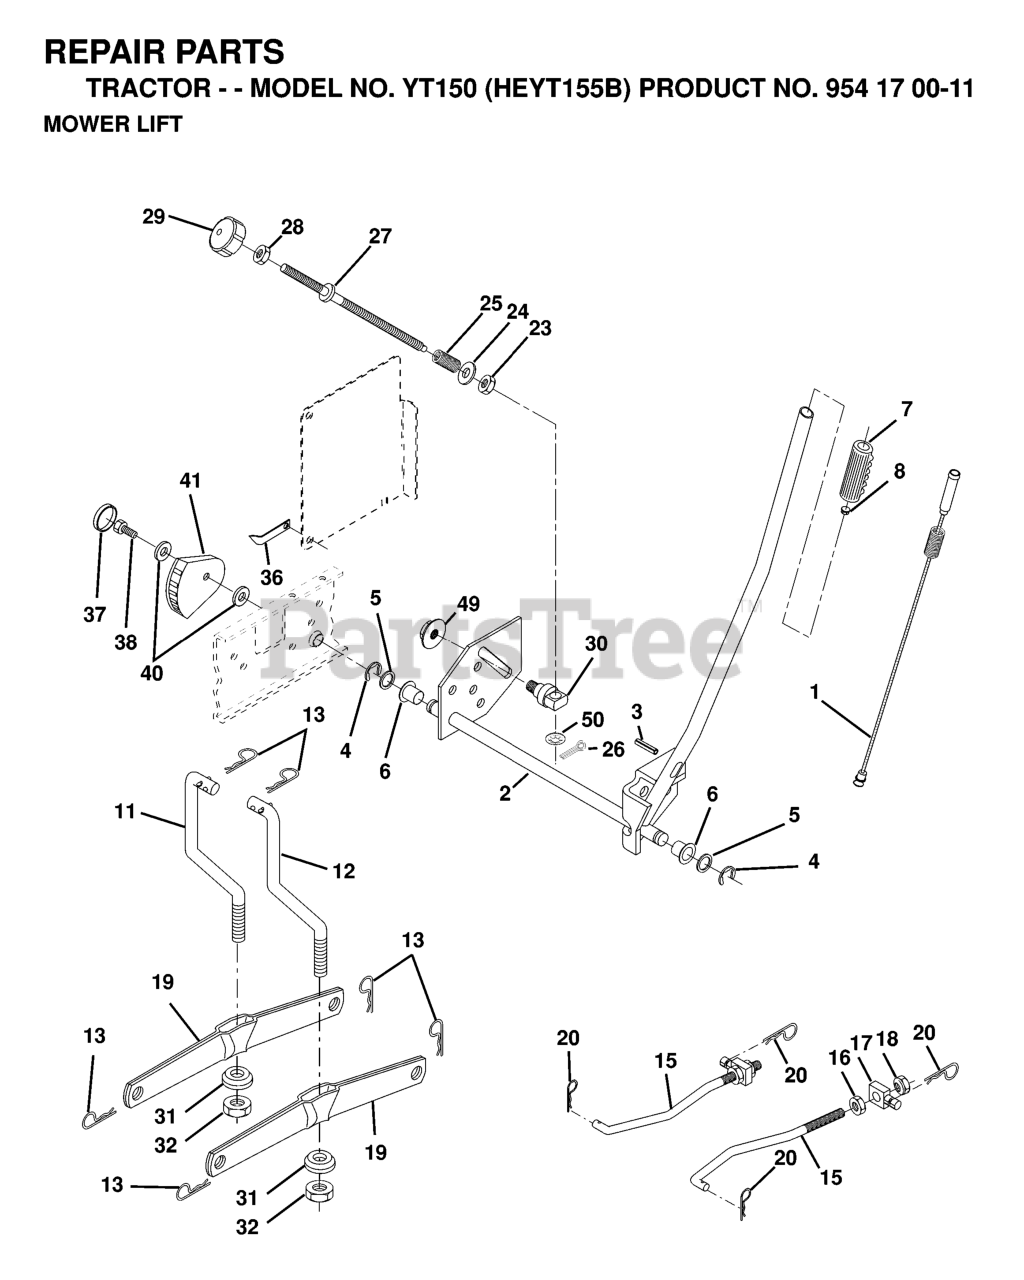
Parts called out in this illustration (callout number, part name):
1	WIRE ASM INNER W/ PLUNGER LT
2	SHAFT ASM R HANDLE
3	PIN GROOVE.
4	RETAINING RING LT
6	BEARING.NYLON
7	GRIP HANDLE
8	PLUNGER BUT KIT
11	LINK LIFT LH
12	LINK LIFT RH
13	RETAINER-SPRNG RB
15	FRONT LINK
16	NUT.HEX.JAM.1/2-13
17	TRUNION
18	NUT.LK.W/WSH.1/2.
19	ARM.REAR.SUSPENSION
20	SPRING RETAINER
25	SPRING**
26	COTTER PIN
27	ROD ADJ LIFT
28	NUT
29	KNOB INF 3/8-16
31	BEARING PIVOT
32	NUT CROWNLOCK 3/8-24
36	POINTER, HEIGHT INDICATOR(2 2)
38	SCREW.THDROL.5/16-18X3/4.TTY
41	IND. HEIGHT STLT
49	NUT
50	NUT PUSH M
